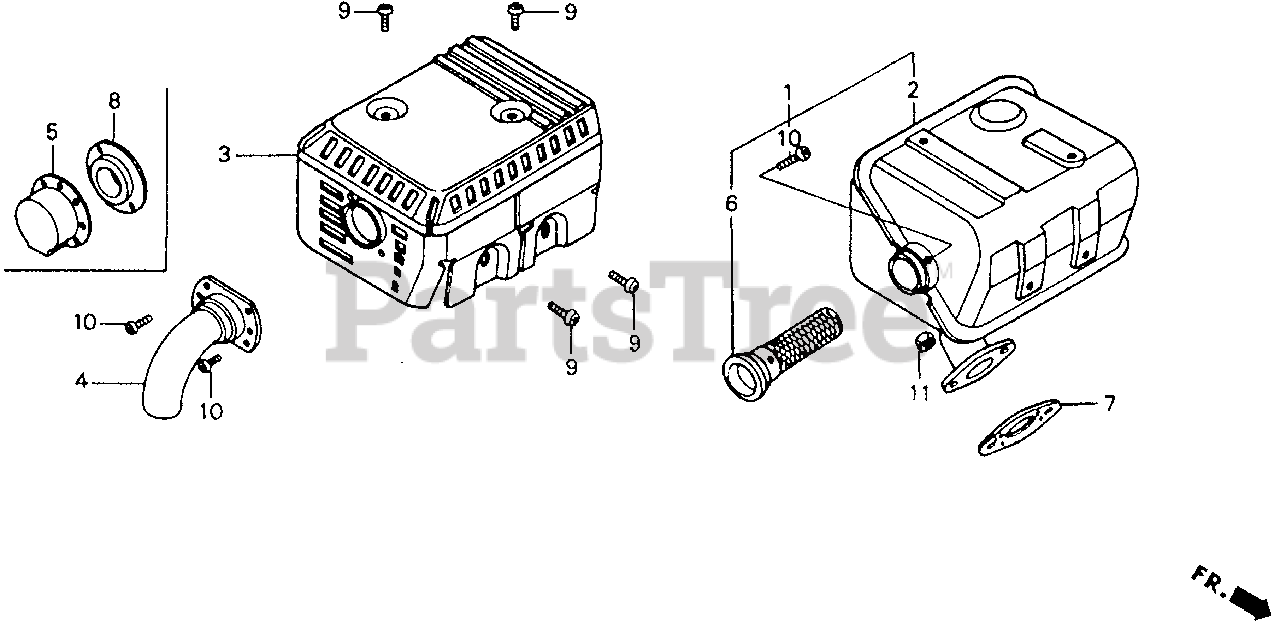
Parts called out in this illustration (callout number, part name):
1	MUFFLER (ARRESTER)
3	PROTECTOR (UPPER)
3	PROTECTOR, MUFFLER
5	DEFLECTOR
6	ARRESTER, SPARK
7	GASKET, MUFFLER
8	GUIDE, MUFFLER
9	SCREW, TAPPING (5X8)
10	SCREW, TAPPING (4X6)
11	NUT, HEX. (8MM)
